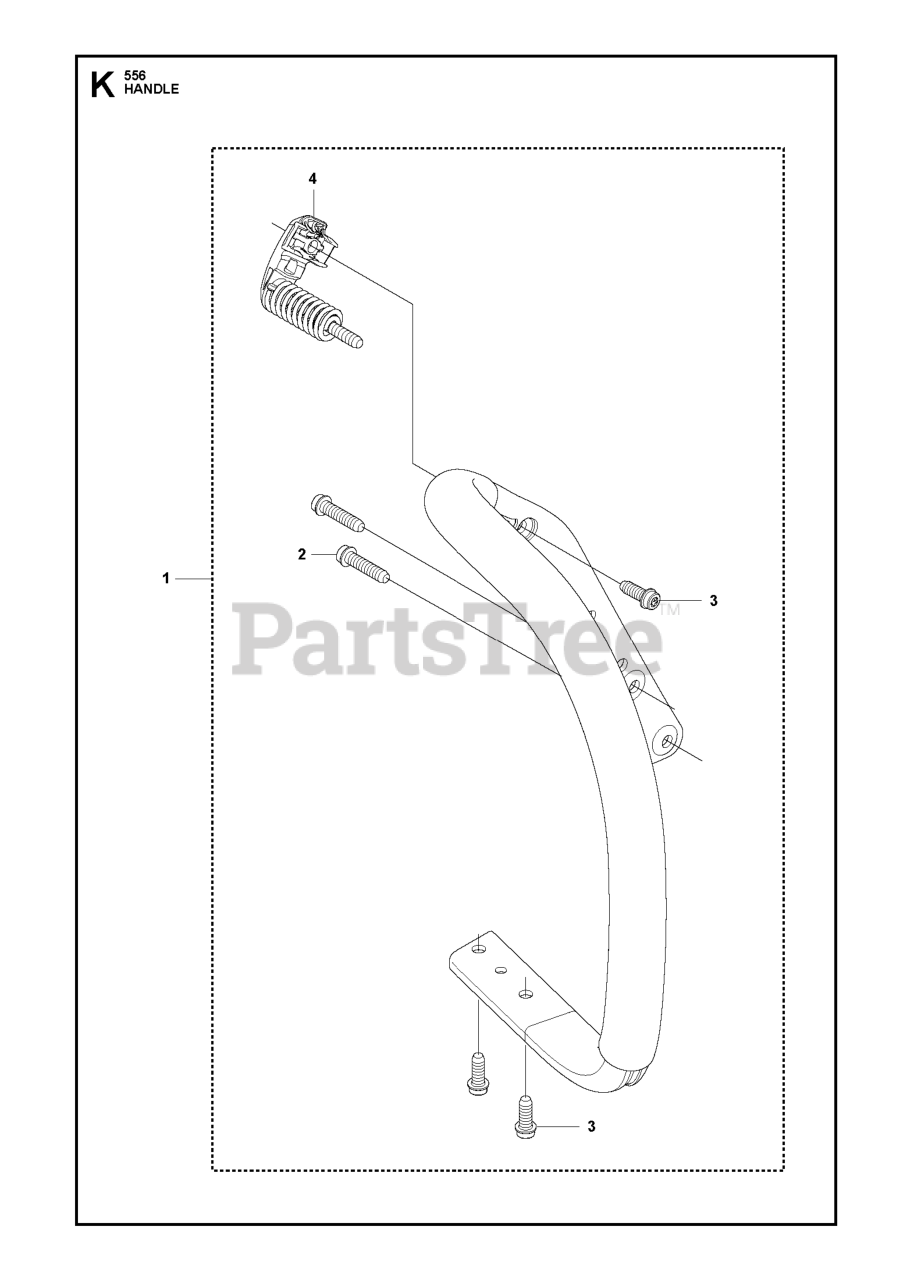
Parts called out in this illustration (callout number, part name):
1	DECAL.WARNING.COMBINED.T/CRD
2	DECAL.ENGINE.WARNING
3	DECAL.BADGE.170MM.TEXTLOGO.
4	DECAL.RPL.KW.FS541.TCRD.107R
7	DECAL.INSTRUCTION.MLCH/BG.VERT
9	DECAL.WARN.CRDBAGGER.ELECDUMP
11	DECAL.CUTFINGER.CE.02
14	DECAL.CHASSIS.HOT.MUFFLER
21	DECAL DECAL V-BELT 97 CM CRD
